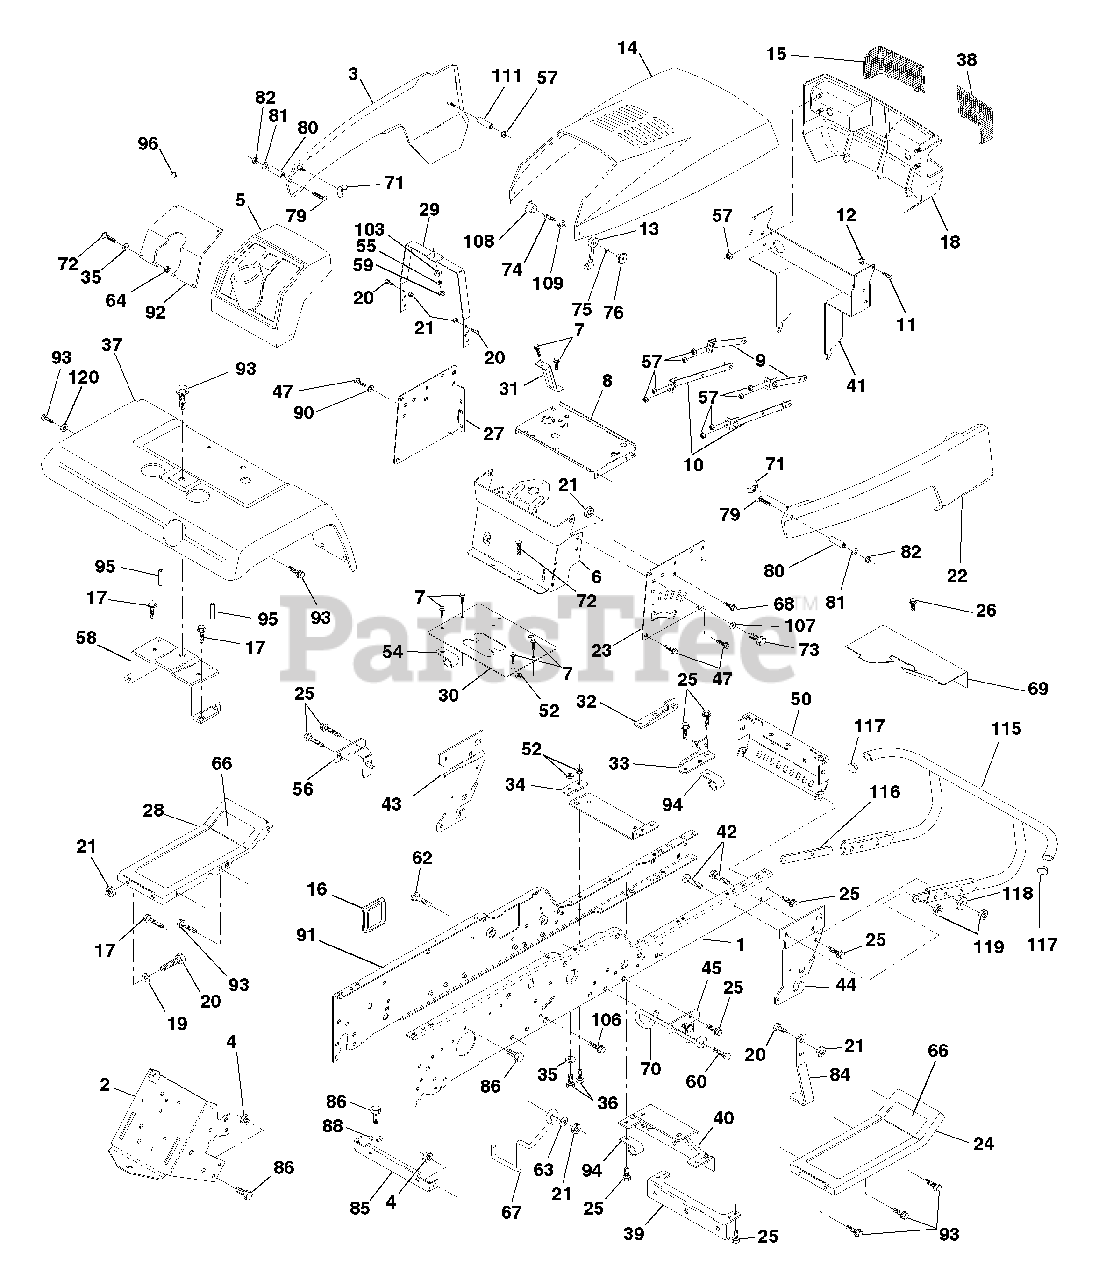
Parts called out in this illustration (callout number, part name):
1	Rail, Frame RH
2	Drawbar, Gt
3	Panel Asm., Side LH
4	Nut, Lock Hex 7/16 Unc
5	Dash, Plastic Black
6	Dash Asm., Lower
7	Screw, Thd Cut 1/4-20 x 1/2
8	Support, Battery
9	Strap, Asm. Hinge Front
10	Strap, Asm. Hinge Rear
11	Bolt Shoulder 1/4-20
12	Nut, Lock W/Ins 1/4-20
13	Latch, Chute Blk
14	Hood Asm., Pnt
15	Lens, Headlight LH
16	Cover, Access
17	Screw, Thdrol 3/8-16 x 3/4
18	Grille
19	Washer 13/32 x 13/16 x 12 Ga.
20	Bolt, Fin Hex 3/8-16 x 1
21	Nut, Lock Hex W/Wsh 3/8-16 Unc
22	Panel Asm., Side RH
23	Panel, Dash Side RH
24	Footrest, RH
25	Screw, Thdrol 3/8-16 x 3/4
26	Screw, Thdrol 5/16-18 x 3/4
27	Panel, Dash Side LH
28	Footrest, LH
29	Bracket, Support Dash
30	Saddle, Slkscr Vgt
31	Brace, Support Steering
32	Bracket Asm., Frame Pivot Lh
33	Bracket Asm., Frame Pivot Rh
34	Bracket, Engine Support Rear
35	Washer 11/32 x 11/16 x 16 Ga.
36	Bolt, Fin Hex 5/16-18 x 3/4
37	Fender, Pnt.
38	Lens Headlight RH
39	Bracket, Axle Front
40	Bracket, Support Axle/Engine
41	Support Asm. Grille
42	Bolt, Carriage 3/8-16 x 1
43	Bracket, Spnsn Front Lh
44	Bracket, Spnsn Front Rh
45	Bracket Asm., Susp Chassis Rh
47	Screw Thdrol 3/8-16 x 1/2
50	Bracket, Chassis Front
52	Locknut, Hex W/Ins 5/16-18 Unc
54	Clip, insulated
55	Washer 9/32 x 3/4 x 16 Ga.
56	Bracket Asm., Susp Chassis Lh
57	Nut Keps Hex 1/4 -- 20
58	Bracket Asm., Fender
59	Nut, Fin Hex 1/4-20
60	Screw Thdrol 3/8-16 x 1-1/4
62	Bolt, Carriage 3/8-16 x 1 Gr. 5
63	Washer 13/32 x 3/4 x 14 Ga.
64	Nut 5/16-18
66	Pad, Footrest
67	Guide, Belt
68	Screw, Thdrol 5/16-18 x 1/2
69	Shield, Heat
70	Guide, Belt Mid Span
71	Nut, Plastic Locking Wing 1/4-20
72	Screw, Mach Trhd 5/16-18 x 3/4
73	Bolt, Fin Hex 3/8-16 x 1 Gr. 5
74	Screw, Machine #10-24
75	Washer, Lock Of O
76	Nut, Weld #10-24
79	Screw, Machine #10-24 x 1/4
80	Spacer, Split
81	Washer 7/32 x 1/2 x 18 Ga.
82	Nut 010-24
84	Stop, Over Center Mower
85	Bracket, Support
86	Bolt, Fin Hex 7/16-14 Unc x 1
88	Washer, Lock Hvy Hld Sp 7/16
90	Washer, Lock External Tooth 3/8
91	Rail, Frame Lh
92	Plate, Silkscreen Dash
93	Screw, Thdrol 3/8-16 x 1/2
94	Clip, Fuel Line
95	Push Nut, Nylon
96	Plug, Hole
103	Washer, Lock 1/4
106	Bolt 5/16 - 18 Type TT
107	Washer 13/32 x 1 x 14 Ga.
108	Cap, Snap Black
109	Cap, Washer Snap
115	Bumper Asm.
116	Bracket, Extension, Bumper
117	Plug, Plastic
118	Washer 13/32 x 13/16 x 16 Ga.
119	Nut Crownlock 3/8-16 UNC
120	Washer 13/32 x 1 x 16 Ga.
